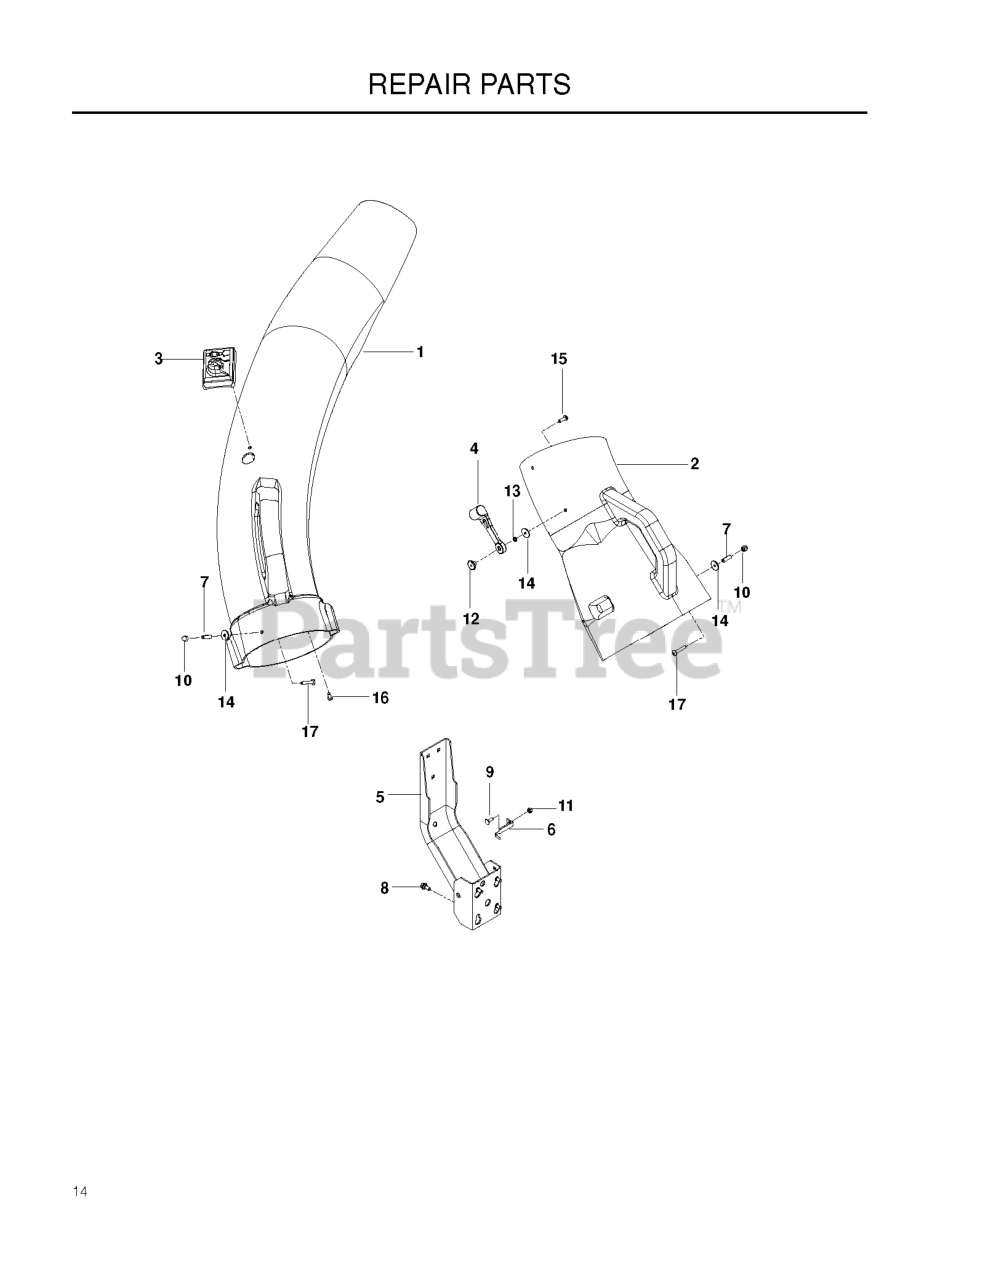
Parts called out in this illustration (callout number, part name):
1	UPPER CHUTE 54"
2	CHUTE, MIDDLE - TRIMMED
3	DUMP BAG INDICATOR
4	HOOD LATCH
5	POST.SUPPORT.BAGGER.BLACK
6	STOP BRACKET, BAGGER 2 BIN
7	BSHG .202X.75 LG SPLIT ZD SPEC
8	SHOULDER BOLT 5/16-18TT
9	RHSNB 1/4C X 3/4
10	NUT 10-24 ACORN ZD
11	NUT.1/4-20.HEX.NYLOC.ZD
12	NUT 10-24 WELD PLATED
13	WASHER - 3/16 LOCK ZD
15	SCREW #10-24 X 5/8
16	SCREW
17	SCREW #10-24 X 1-1/8 ZD SPEC
